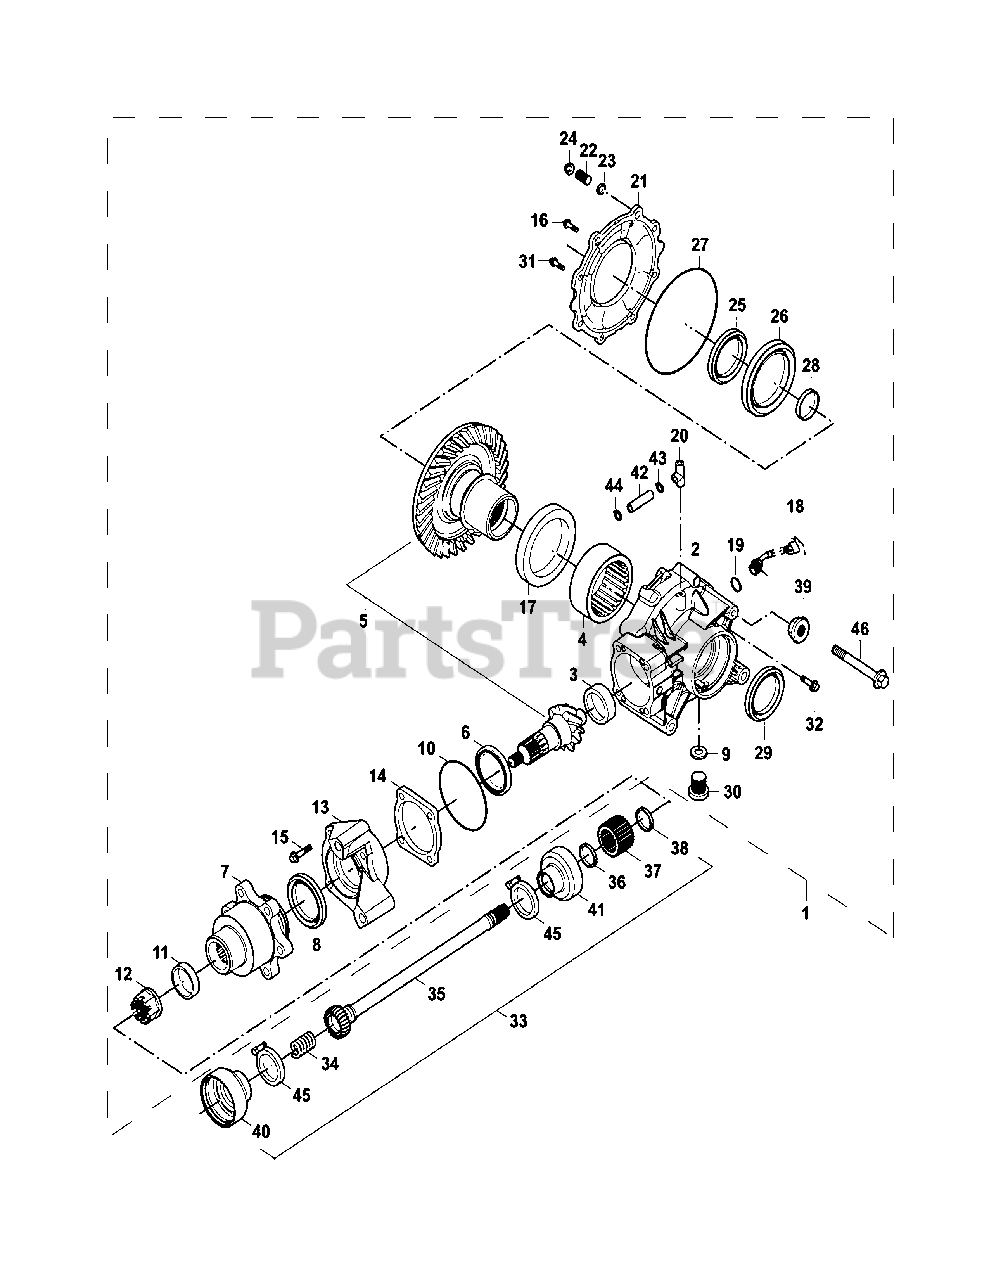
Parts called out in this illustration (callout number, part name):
1	Rear Reducer Assy
2	Rear Reducer Case I
3	Bearing 22x30x13
4	Bearing 55BM672055x67x20
6	Bearing 25x62x17
7	Mount Bracket,Rear Disk Brake Plate
8	Oil Seal 61x35x9
9	Fuel Drain O-Ring Seal 13x1.5
10	O-Ring Gasket 3x71
11	Washer 12x30x4
12	Hexagon Flange Nut M12x1.25
13	Mount Bracket, Rear Brake Caliper
14	Rear Adjustment Gasket I
15	Hexagon Bolt With Washer
16	Socket Hexagon Screw M8x25
17	Rear Adjustment Gasket II
18	Speed Sensor Comp.
19	O-Ring Gasket, Fuel Injection2.3x19.4
20	Vent Pipe, Rear Reducer
21	Rear Reducer Case II
22	Socket Hexagon Screw M8x45
24	Hexagon Flange Nut M8
25	Oil Seal65x90x9
26	Bearing 16017C2 85x130x14
27	O-ring 3x150
28	Adjust Cushion III
29	Oil Seal65x90x9
30	Fuel Drain Screw Plug
31	Hexagon flange nut M10x1.25x25
32	Hexagon Flange Bolt M8x12
33	Rear Transmission Shaft Comp
34	Spring 18.5x2x30
35	Rear Transmission Shaft
36	Circlip D0=19
37	Jointsleeve,Rear Axle Transmission Shaft
38	Elasticity Block Ring D0=22
39	Hexagon flange nut M10x1.25
40	Front Dust Proof Cover, Rear Differential Shaft
41	Rear Dust Proof Cover, Rear Differential Shaft
42	Vent Pipe, Rear Reducer
43	Steel Wire Clamp8
44	Pipe Clamp 12
45	Clamp20-32
46	Hexagon Flange Bolt M10x1.25x120
